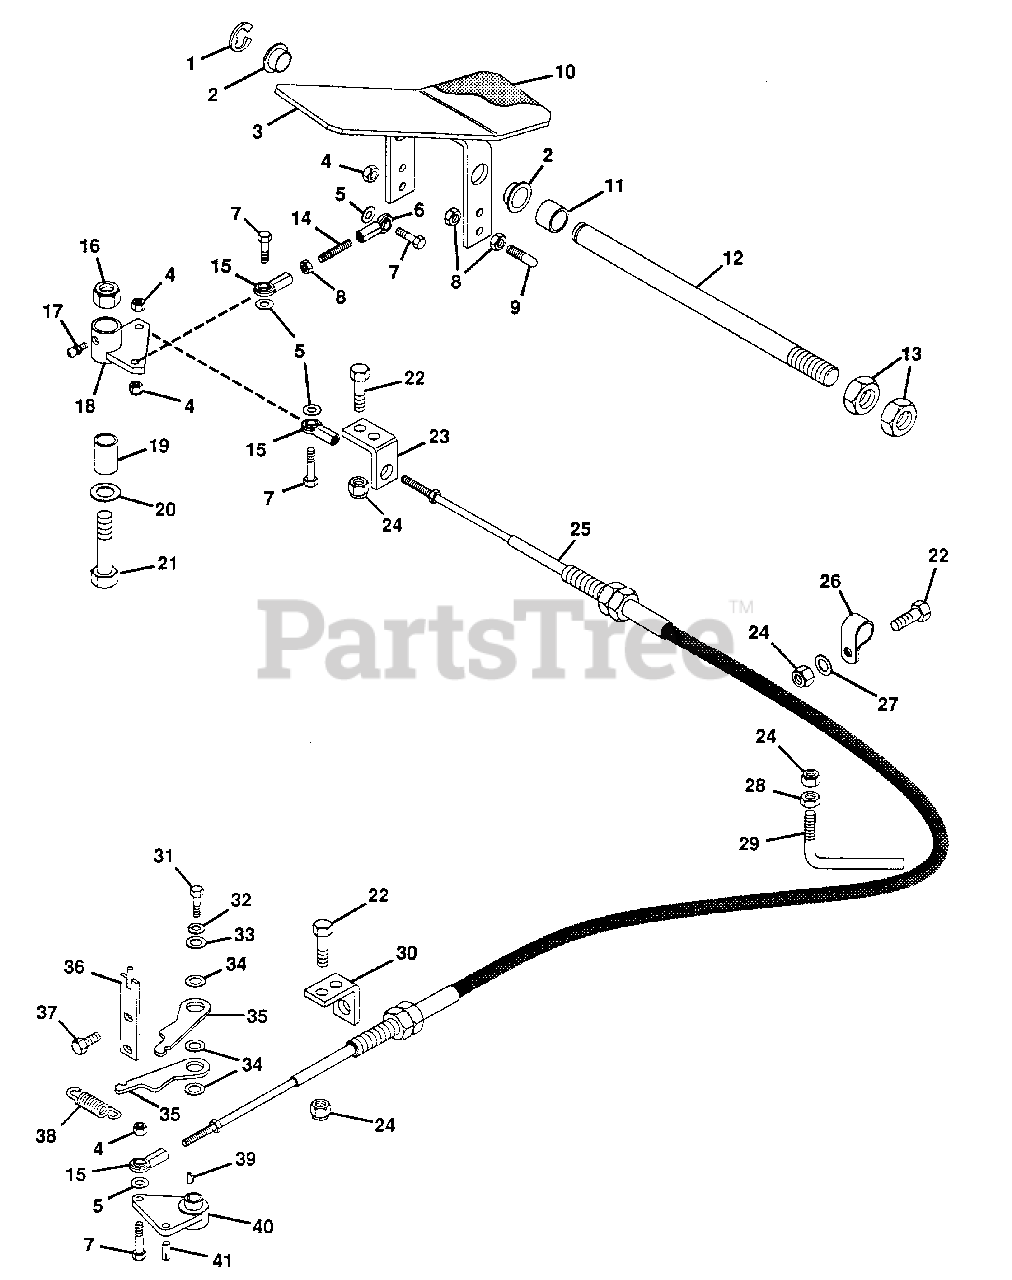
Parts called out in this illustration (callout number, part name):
1	E-RING, .750 SHAFT
2	BUSHING, NYLON .76X1.00X.6 FLG
3	WELDMENT, PEDAL
4	NUT, LOCK 1/4-20
5	WASHER, FLAT .281X.625X.065
6	ROD END, L.H.
7	BOLT, HEX 1/4-20X1.25
8	NUT, JAM 1/4-28 HEX
9	ROD, ACTUATOR
10	COVER, PEDAL
11	SPACER
12	SHAFT, PEDAL
13	NUT, JAM 3/4-16 HEX
14	ROD
15	ROD END, FEMALE 1/4-28
16	NUT, LOCK 1/2-13
17	FITTING, LUBE 1/4-28
18	WELDMENT, LEVER
19	SPACER, .50X.875X1.966
20	WASHER, FLAT .500X1.250X.083
21	BOLT, HEX 1/2-13X2.50
22	BOLT, HEX 3/8-16X1.00
23	BRACKET, CABLE
24	NUT, LOCK 3/8-16
25	CABLE, FWD-REV
26	CLAMP, NYLON
27	WASHER, FLAT .406X.812X.065
28	NUT, JAM 3/8-16 HEX
29	ROD, CABLE GUIDE
30	BRACKET, CABLE
31	BOLT, HEX 1/4-20X1.50
32	WASHER, LOCK 1/4 REG.
33	WASHER, FLAT .265X1.250X.063
34	WASHER
35	LEVER, NEUTRAL RETURN
36	WELDMENT, NEUTRAL STOP
37	BOLT, SELF-TAPPING 5/16-18X.62
38	SPRING, EXT. .62X.75X11.8 RATE
39	KEY, WOODRUFF .125X.50 HRD #3
40	ARM, TRANSMISSION CONTROL
41	PIN, GROOVE
